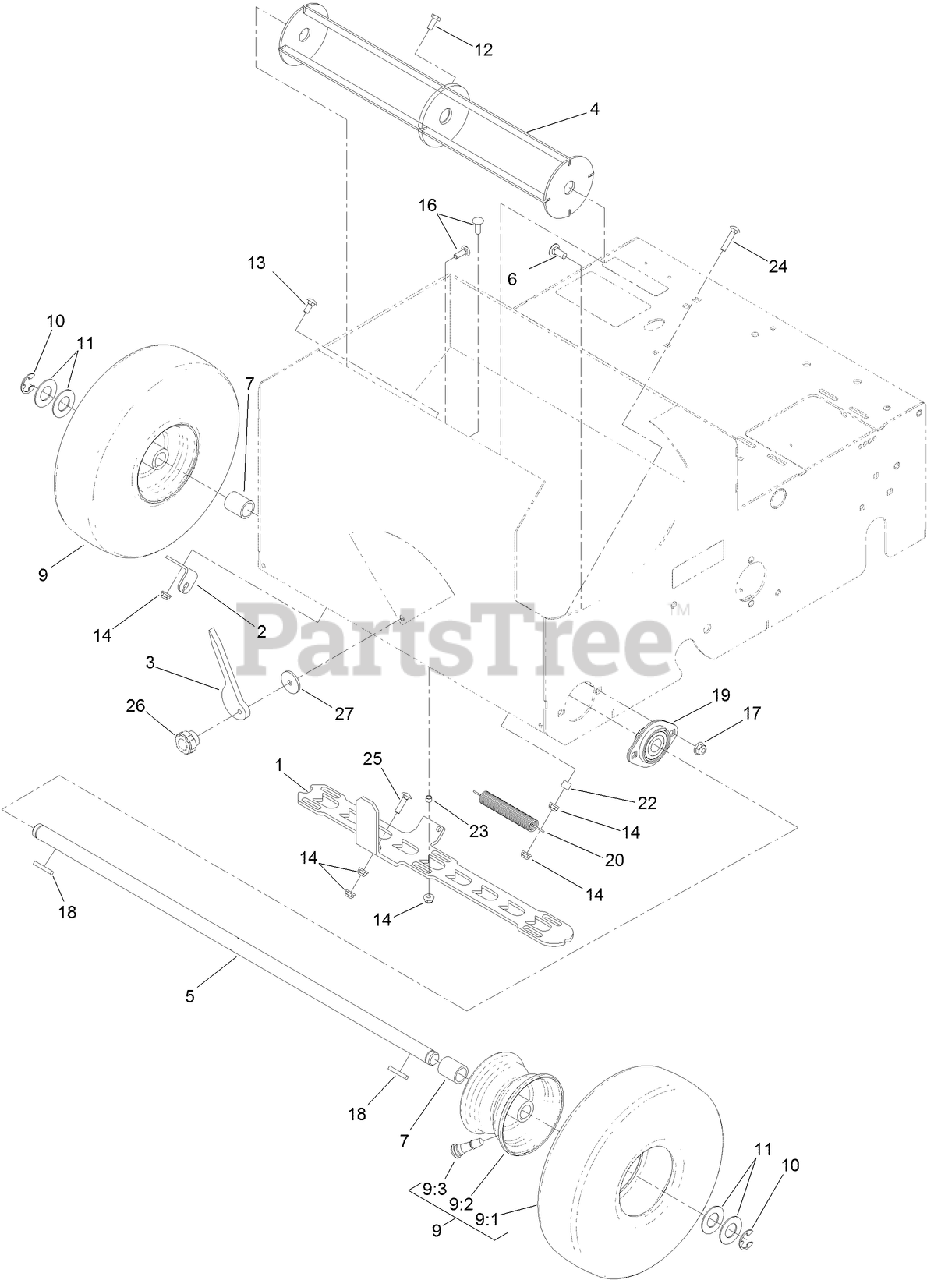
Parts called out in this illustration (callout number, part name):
1	GATE-SEED
2	BRACKET-SEED FLOW
3	GAUGE-SEED FLOW
5	AXLE-FRONT
6	SCREW-CARR
7	Spacer
9	WHEEL ASM
9:2	WHEEL-RIM
9:3	VALVE
10	E-RING
11	WASHER-FLAT
12	SCREW-HH
13	SCREW-CARR
14	NUT-HF
16	BOLT-CARR
17	NUT-HF, NI
18	KEY-SQUARE
19	BEARING
20	SPRING-EXTENSION
22	SPACER
23	SPACER
24	SCREW-CARR
25	Screw, Truss HD 1/4-20 x 1
26	KNOB-CHUTE
27	WASHER
